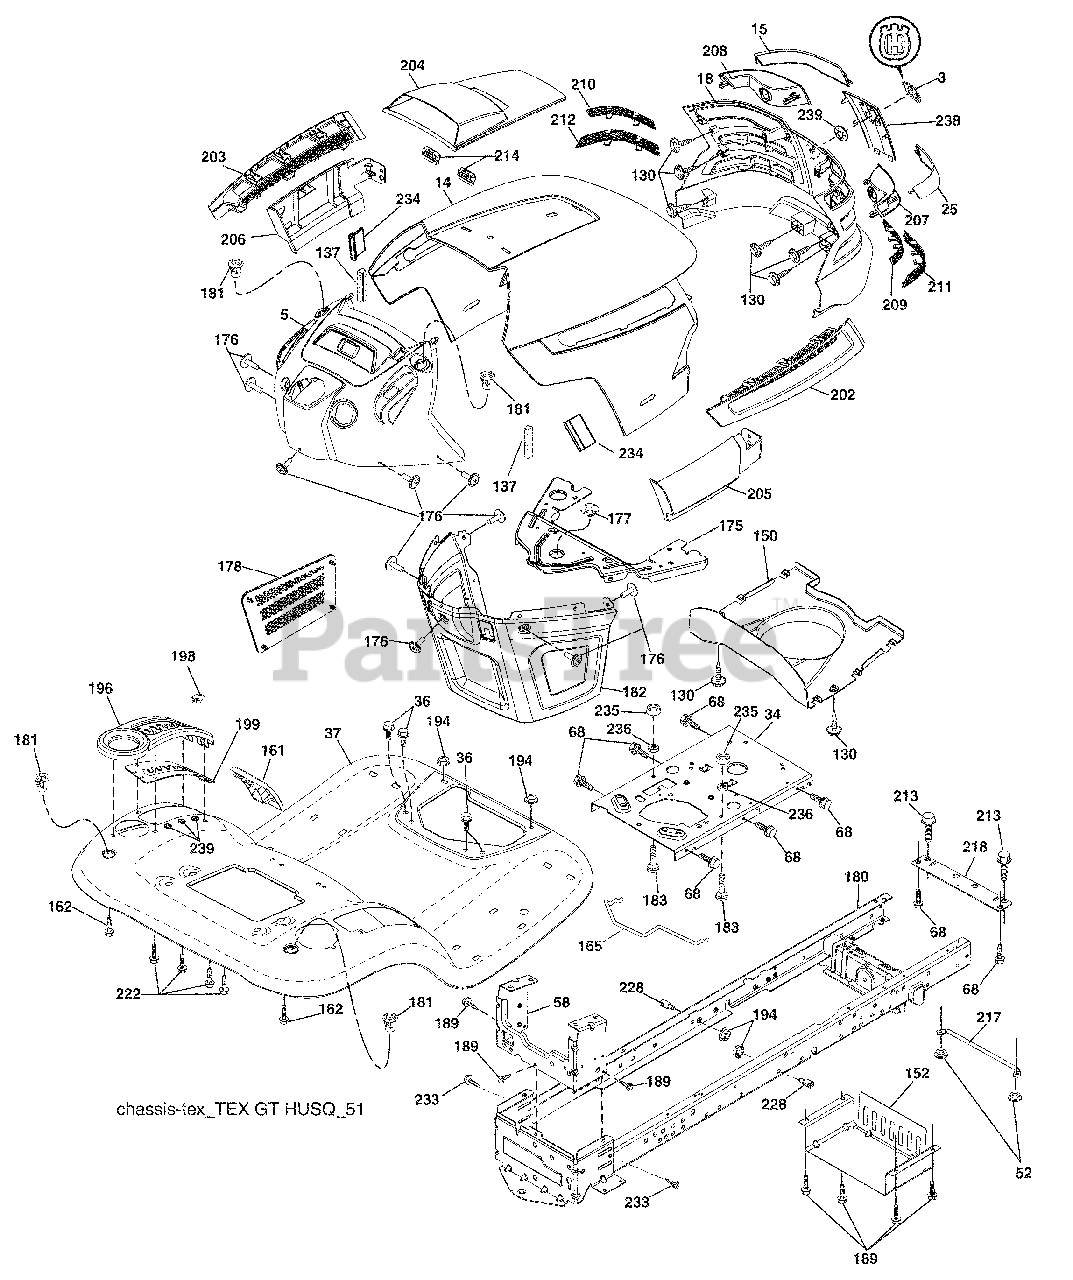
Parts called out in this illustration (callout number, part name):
3	Logo
14	Hood
18	Grille/Lens Asm.
34	Plate Engine
36	Screw 5/16-18 x 3/4
52	Nut Lock 5/16-18
58	Drawbar Upper
68	Screw Thdrol. 5/16-18 x 1/2
130	Screw #10 x 0.750
137	Bumper Dash
152	Shield Browning
161	Console Fuel Window
165	Support Tank Rear
175	Crossmember
176	Screw 10-24 x 5/8
177	Bushing Steering
178	Cargo Net Asm.
181	Bushing Mtg. Fender Crgo
182	Dash Lower
183	Bolt Fin. Hex 5/16-18 unc x 1-1/4
189	Screw 5/16-18 x 3/4
194	Nut Lock Hex Flange 5/16-18
196	Console Asm. Deck Lift
198	Indicator Deck Lift
199	Plate Deck Lift
202	Vent Side Hood RH
203	Vent Side Hood LH
204	Vent Top Hood
205	Skirt Hood Side RH
206	Skirt Hood Side LH
209	Insert Hex Top RH
210	Insert Hex Top LH
211	Insert Hex Bottom RH
212	Insert Hex Bottom LH
213	Bolt 5/16-18 x 3/4
214	Clip Retainer
218	X-Piece Hood Stop
222	Screw 1/4-20 x 5/8
228	Stud Fastner
233	Bolt Shoulder
234	Bumper Hood
235	Spacer Fender
236	Nut Lock 5/16-18 unc
